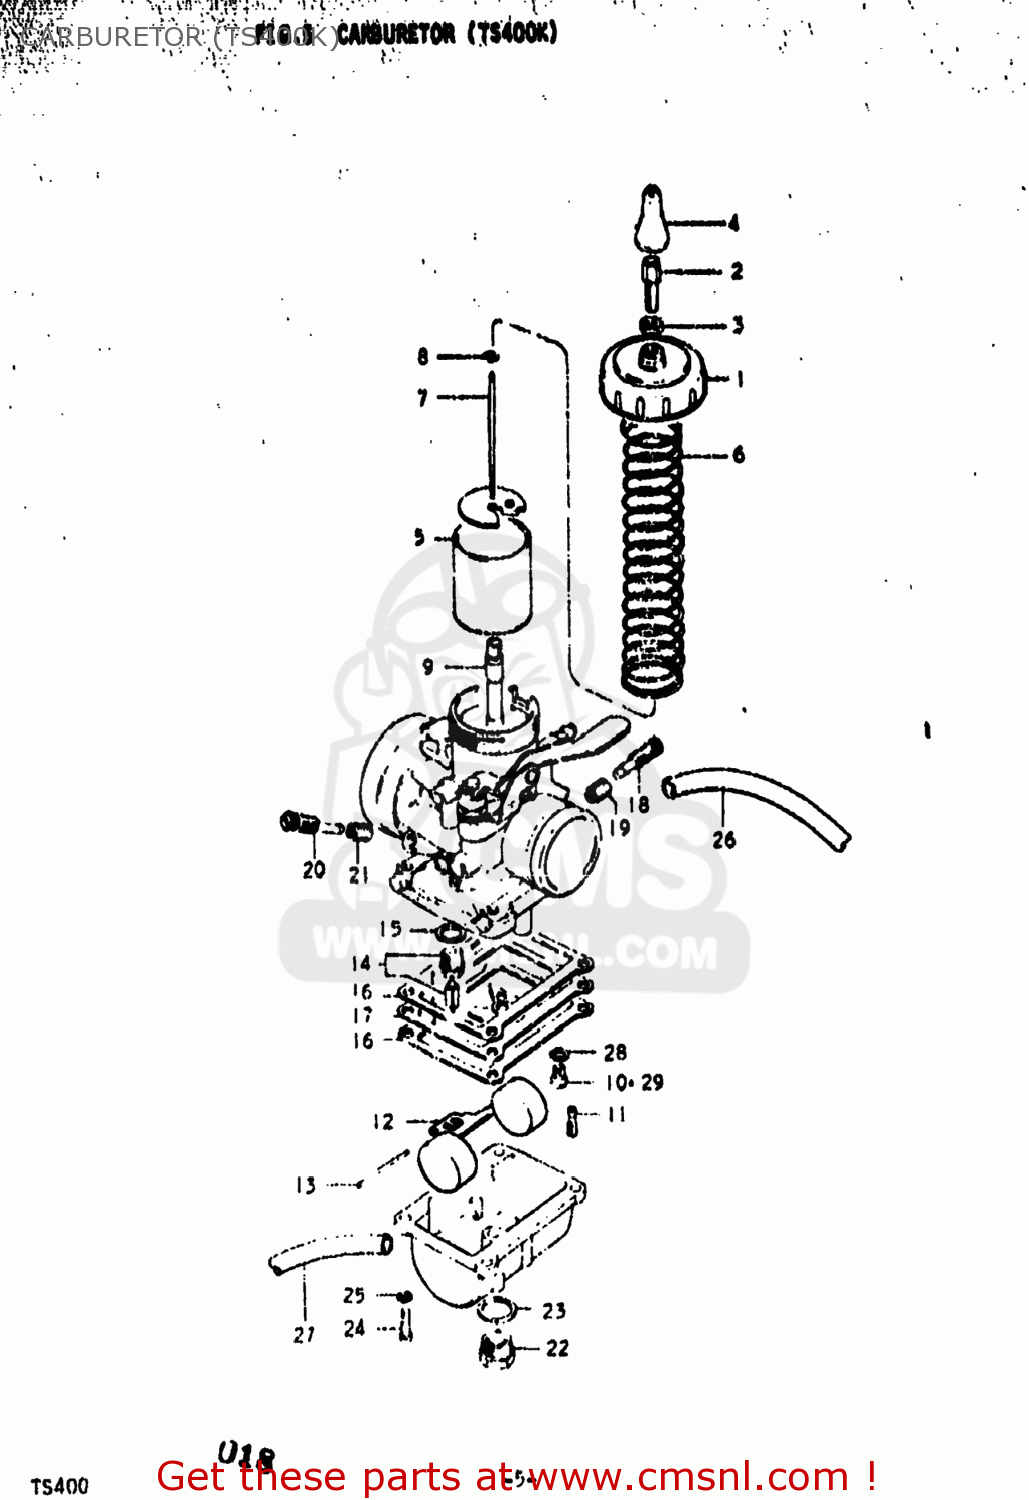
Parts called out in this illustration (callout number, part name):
1	CAP,MIXING CHAMBER
2	ADJUSTER,CABLE
3	NUT
4	CAP,RUBBER
5	VALVE,THROTTLE
6	SPRING
7	NEEDLE JET
8	CLIP
9	JET,NEEDLE
10	JET,MAIN (210)
11	JET,PILOT(40)
12	FLOAT
13	PIN,FLOAT
14	VALVE ASSY,NEEDLE
15	GASKET,MAIN JET HOLDER (NAS)
16	GASKET,FLOAT CHAMBER
17	PLATE
18	ADJUSTER
19	SPRING,THROTTLE SCREW
20	SCREW,PILOT AIR
21	SPRING
22	SCREW,DRAIN
23	GASKET,DRAIN PLUG
24	SCREW 5X20
25	LOCK WASHER
26	HOSE
27	HOSE
28	WASHER
29	JET
